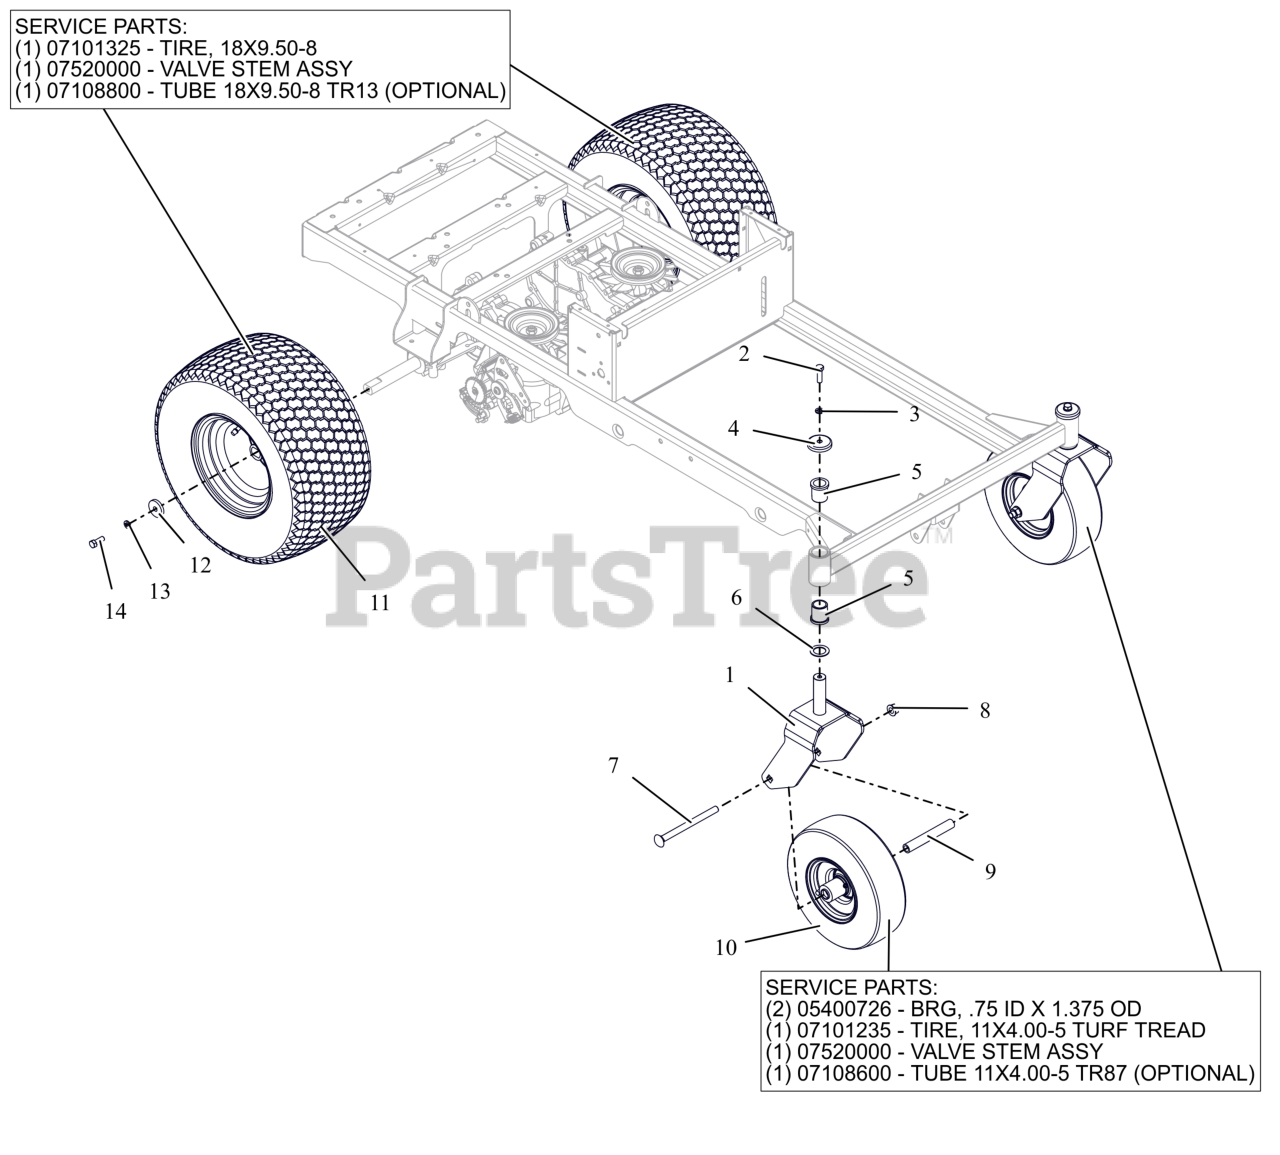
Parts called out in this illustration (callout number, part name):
1	WLDMT- CASTER FORK
2	BLT- HEX .38-16X1.25 G5 ZB500
3	WSHR-LK-REG .375X.094 ZB500
4	SHIELD- AXLE BEARING BLK
5	BSHG-FLG 1.00X1.25X1.50X1.50
6	WSHR-HRD-THRS 1.007X1.542X.062
7	BLT, RHSN .50-13X6.50 G5 ZCC
8	NUT-LK-CTR-FLG .500-13 GG ZCC
9	SPACER, ROLLED WHEEL
10	ASM- WHL/TIRE 11X4.00-5 LG BLK
10	BRG-BALL 1.575X2.677X.590 2RLD
10	LAWN TIRE FRONT, 11/4-5 TURF TREAD
10	VALVE STEM ASS'Y
10	TIRE TUBE, 11/4.0-5 4 PLY TR87 90 BENT VALVE
11	ASM-WHL/TIRE 18 X 9.5-8 LG BLK
11	TIRE, 18X9.50-8
11	CABLE RETAINER
11	TIRE TUBE 18/6.50/8.50/9.50-8, 20/8.00/10.00-8 4 PLY TR13 STRAIGHT VALVE
12	WSHR, FLT .406X1.50X.245 ZCC
13	WSHR,LK-REG .375X.094 ZCC
14	BLT, HEX .38-16X1.00 G8ZCCEP30
